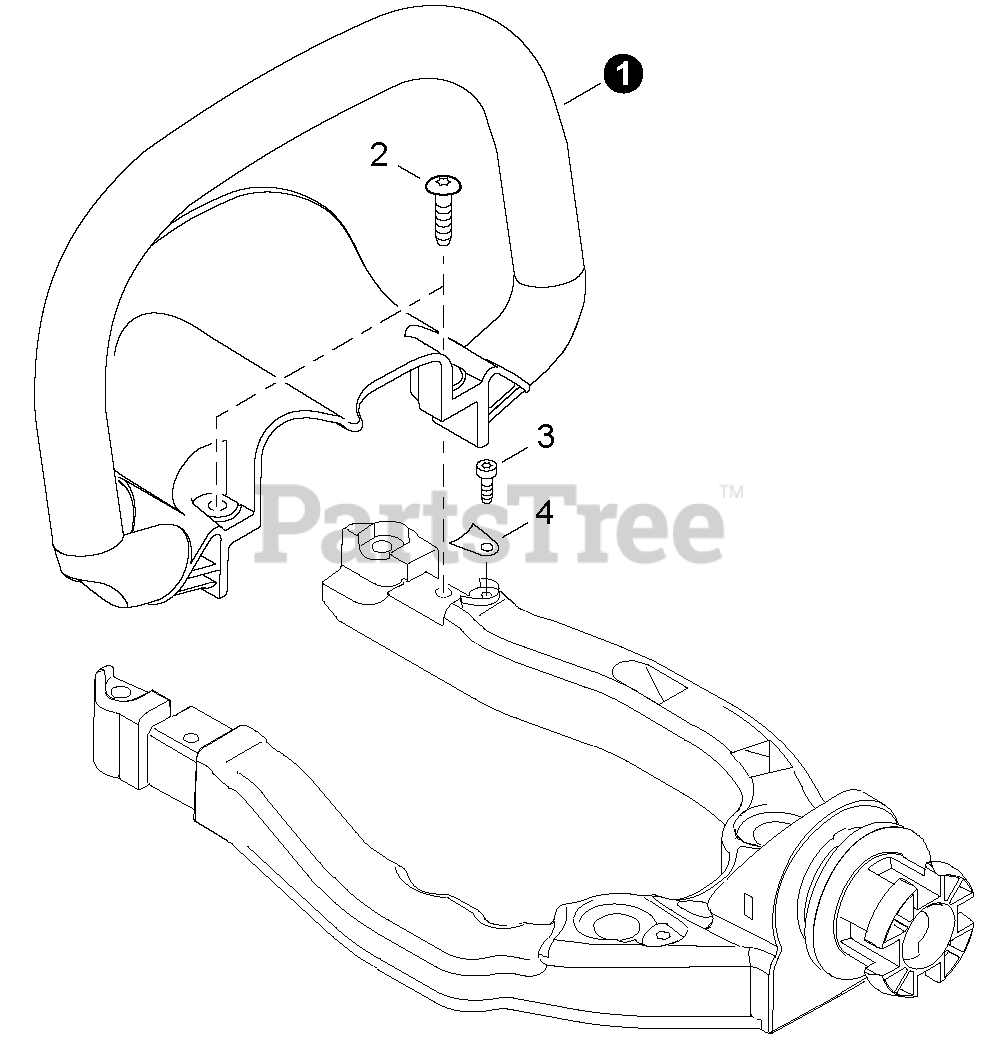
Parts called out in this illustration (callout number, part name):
1	HANDLE, FRONT
2	BOLT, TORX 6
3	BOLT, TORX 4×12
4	PLATE, EYE
